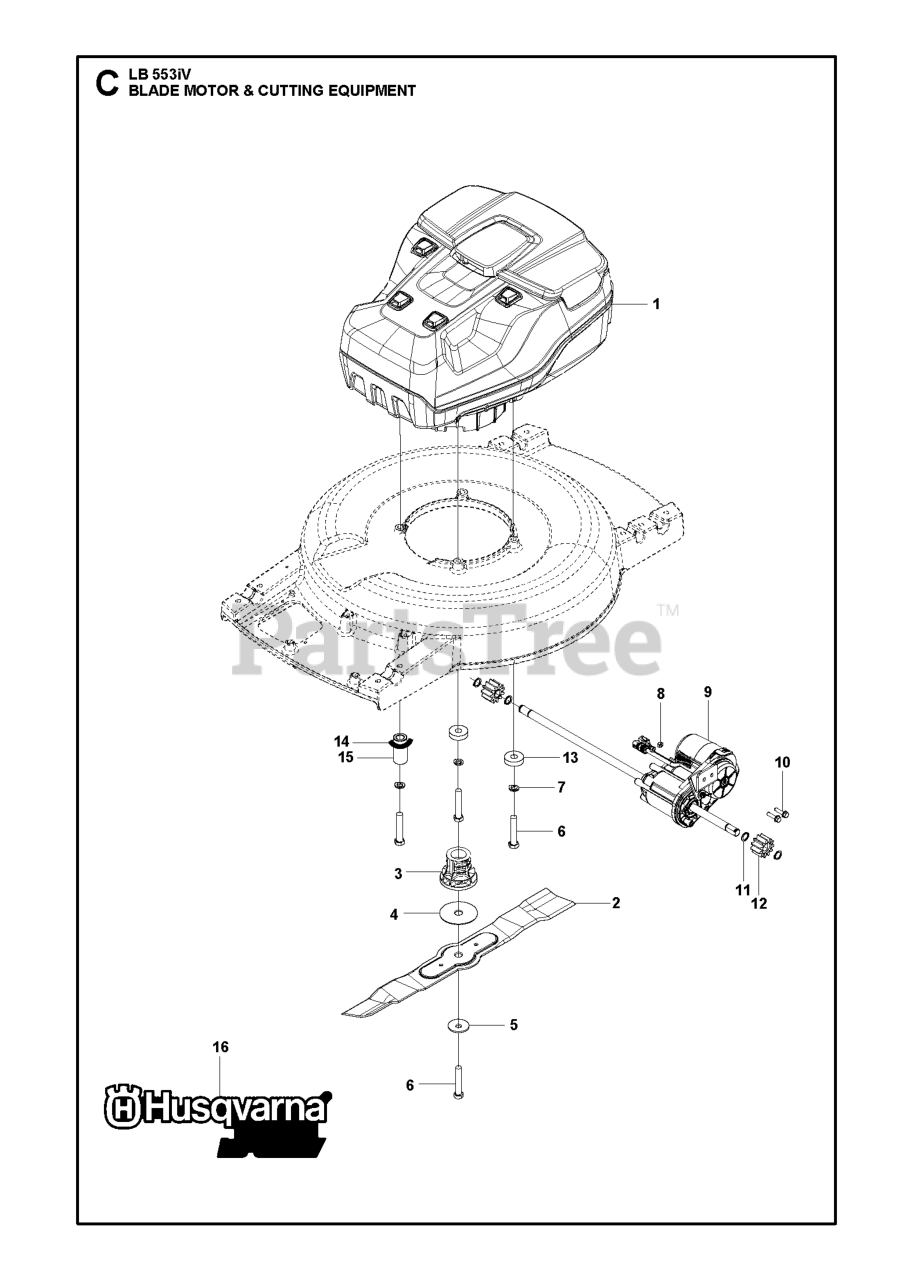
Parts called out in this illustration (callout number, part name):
7	Spring Washer
10	SCREW M6S 5X20
12	PINION PRO
